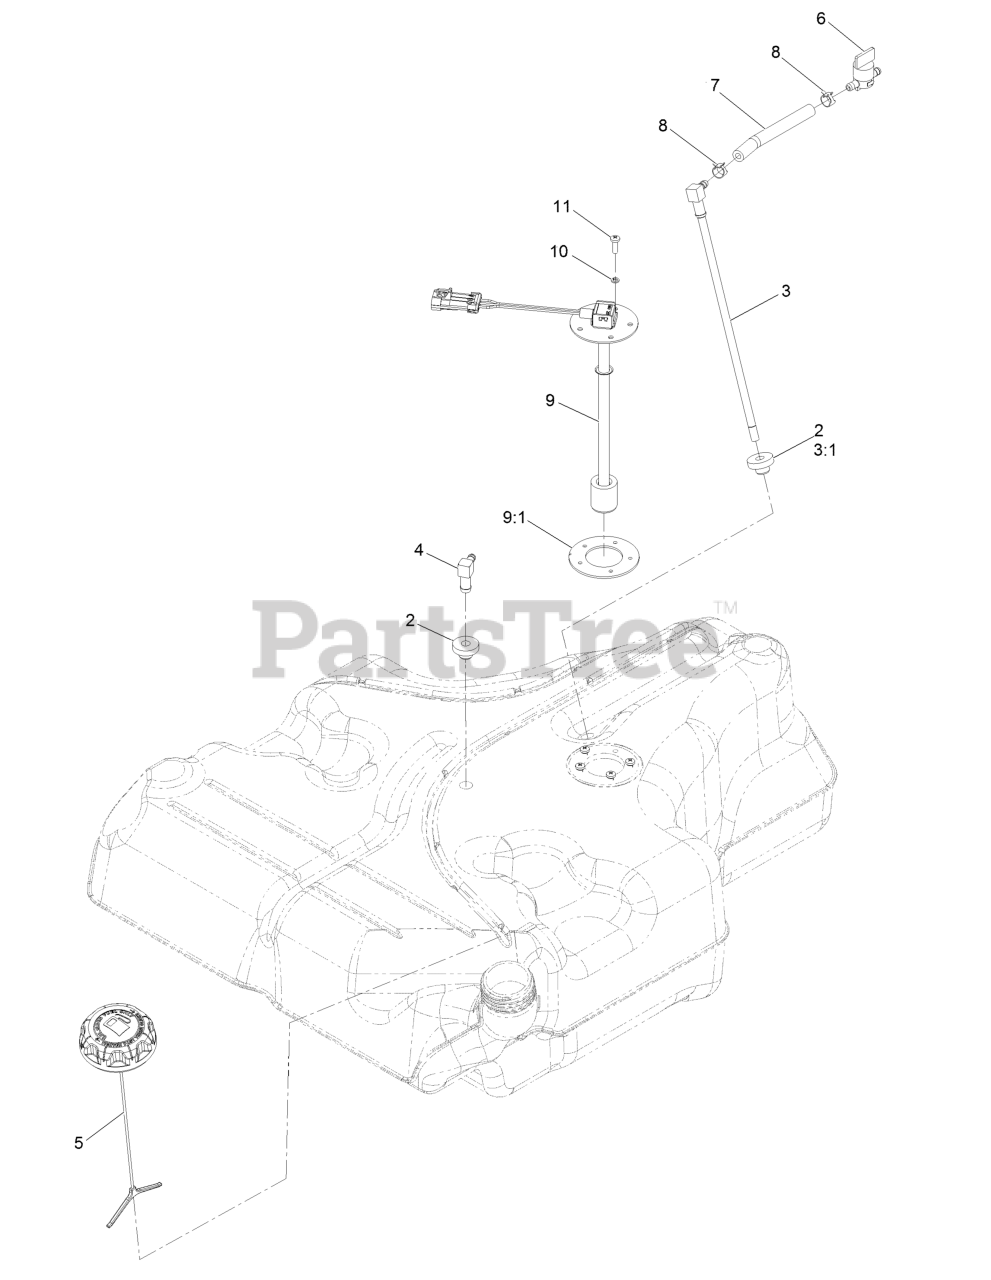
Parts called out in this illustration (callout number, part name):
2	Bushing
3	Fuel Line Kit (With Grommet)
3:1	Bushing
4	Fitting-90 Elbow
5	Cap-Fuel, Ratcheting
6	Valve-Fuel
7	Hose-Fuel
8	Clamp-Hose
9	Sender-Level, Fuel (W/Gasket)
9:1	Gasket-Sender
10	Washer-Lock 3/16
11	Screw-PPH #10-24 X 5/8
